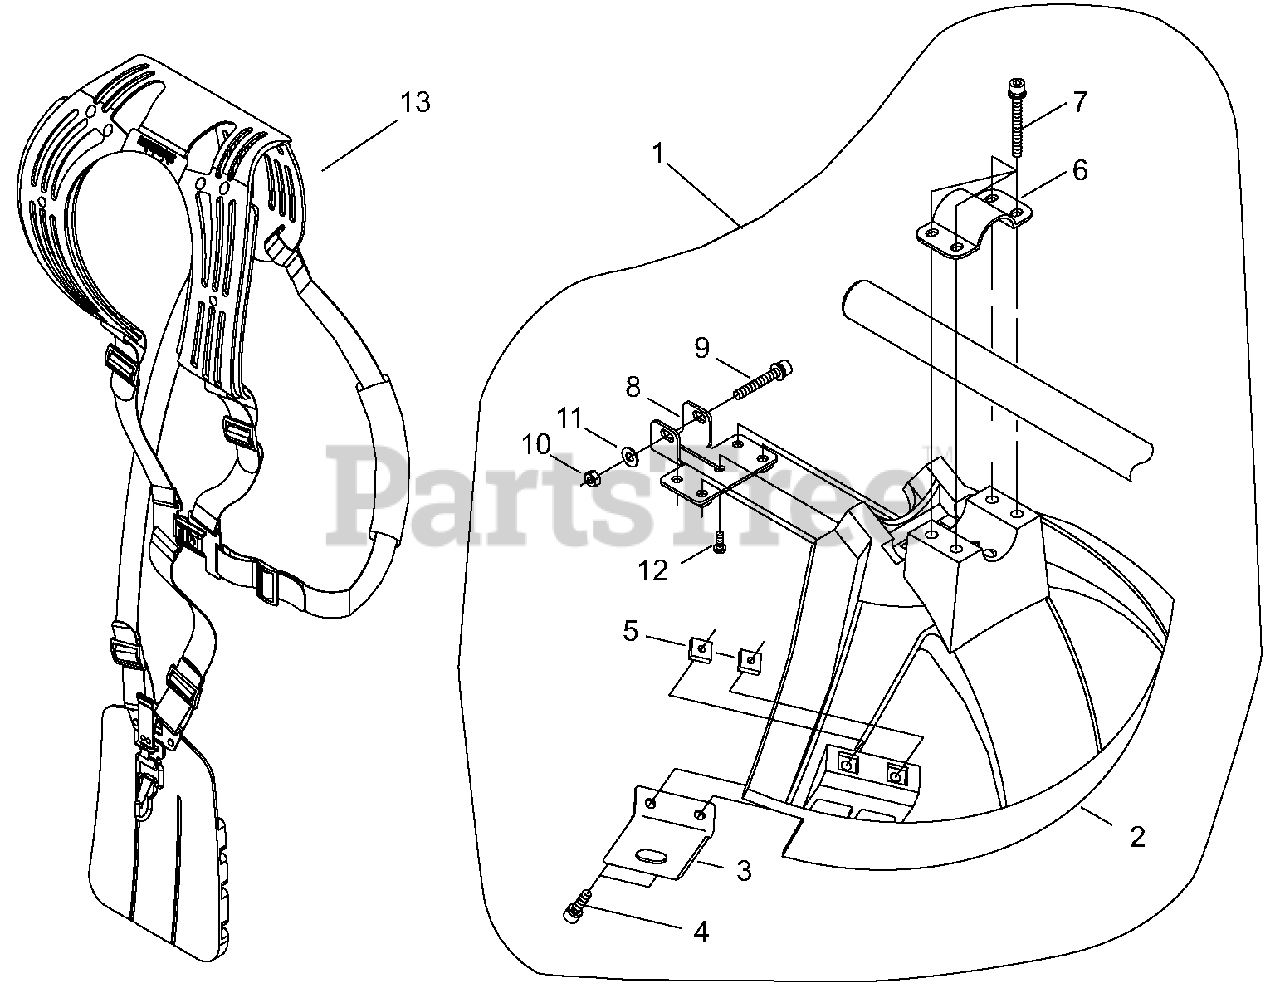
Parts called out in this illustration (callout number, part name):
1	DEBRIS SHIELD ASSY
2	SHIELD, DEBRIS
3	CUTTER
4	BOLT M5×16
5	NUT M5
6	CLAMP, UPPER
7	BOLT M5×45
8	CLAMP, LOWER
9	BOLT M6×40
10	NUT, HEX M6
11	WASHER
12	SCREW HILO 4×10
13	HARNESS ASSY
